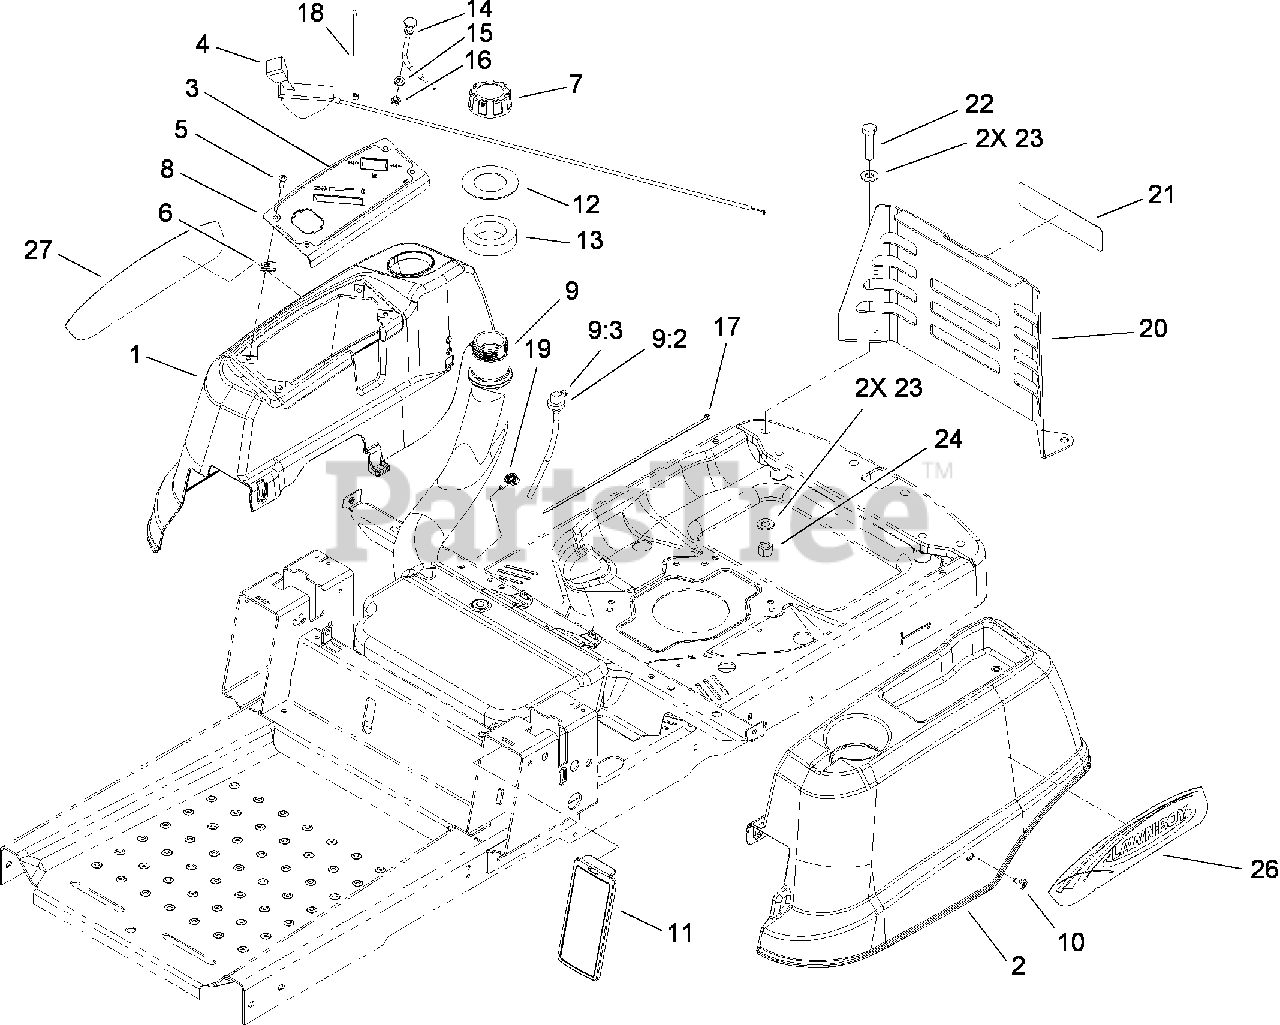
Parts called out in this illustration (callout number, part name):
3	DECAL-PANEL, CONTROL
4	CABLE-THROTTLE
5	SCREW-PRH
7	GAS CAP ASM
8	PANEL-CONTROL
9	FUEL TANK ASM
9:3	FITTING-90 DEGREE
10	SCREW-SHOULDER
11	COVER-CONTROL
12	WASHER-RUBBER
13	SEAL-FOAM
14	CABLE-CHOKE
15	WASHER-LOCK
17	TIE-CABLE
18	STRAP-TIE
19	CLIP-HARNESS
20	SUPPORT-COVER, REAR
22	SCREW-HH
23	WASHER-FLAT
24	NUT-LOCK, NI
26	DECAL-POD, RH
27	DECAL-POD, LH
